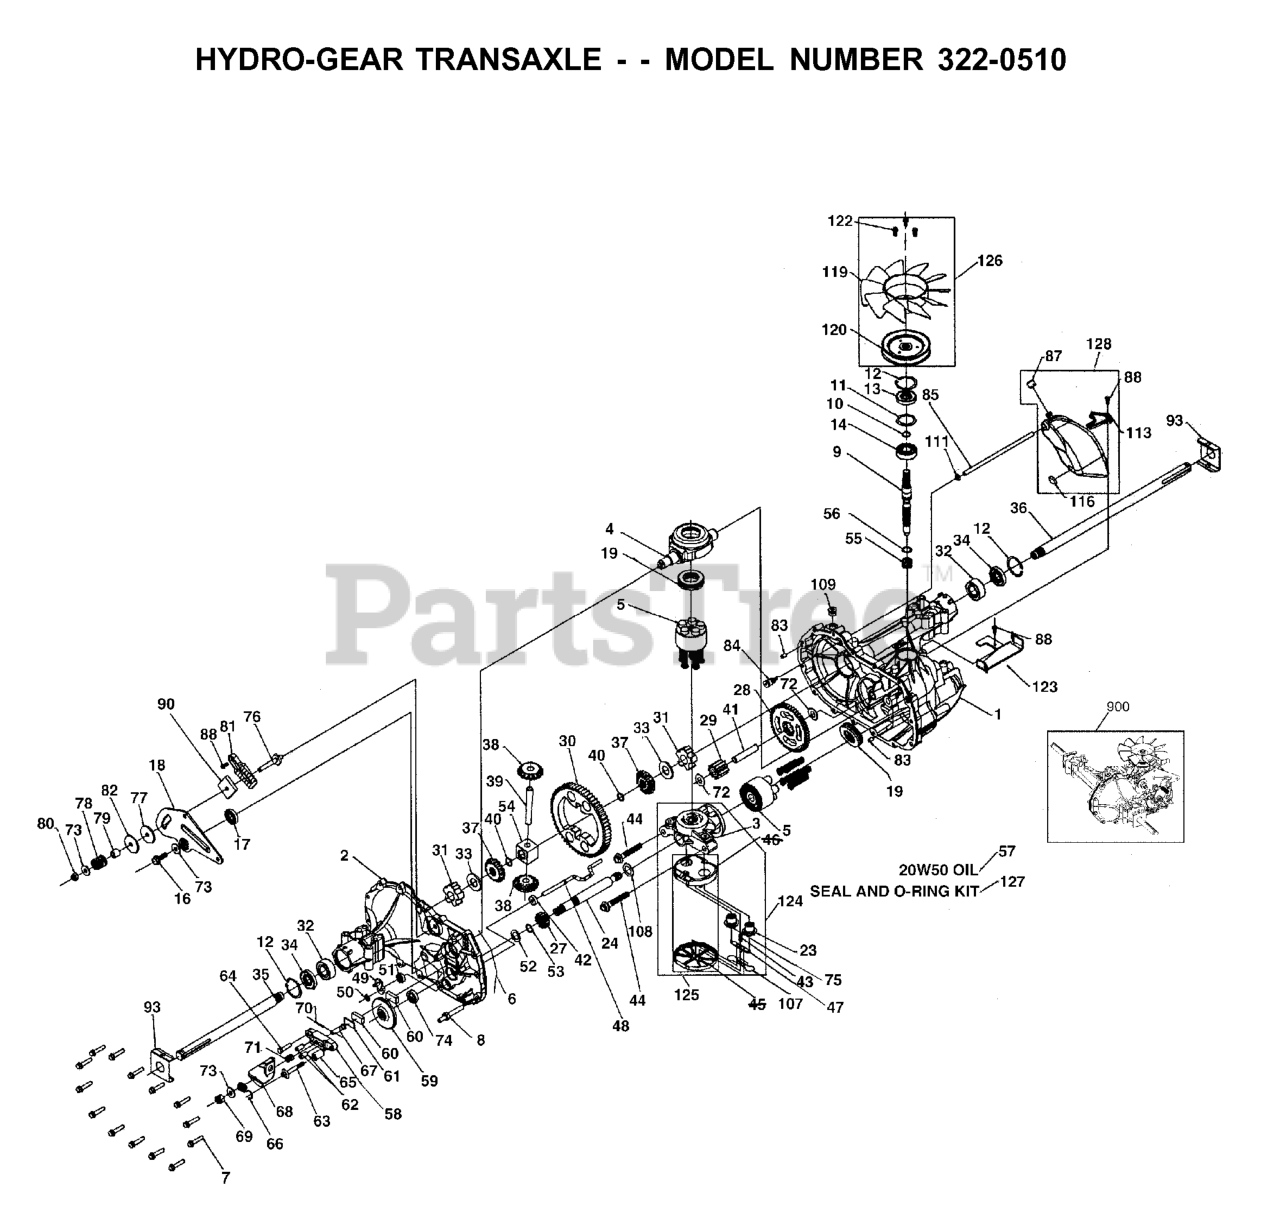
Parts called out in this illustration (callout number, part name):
5	KIT CYLINDER #70331
14	BALL BEARING 17X40X12 50315
33	WASHER.HYDRO-GEAR 44875
39	SHAFT.50146
55	SPRING 2003014
60	BRAKE PUCK (44132)
61	PUCK PLATE 44134
62	BRAKE PIN 44127
64	BOLT W/NYLOCK 44433
73	WASHER .34X.88X.06.44130
78	SPRING HELICAL COMP 50277
79	SPACER.HYDRO GEAR 50278
80	LOCKNUT, HEX 5/16-24
